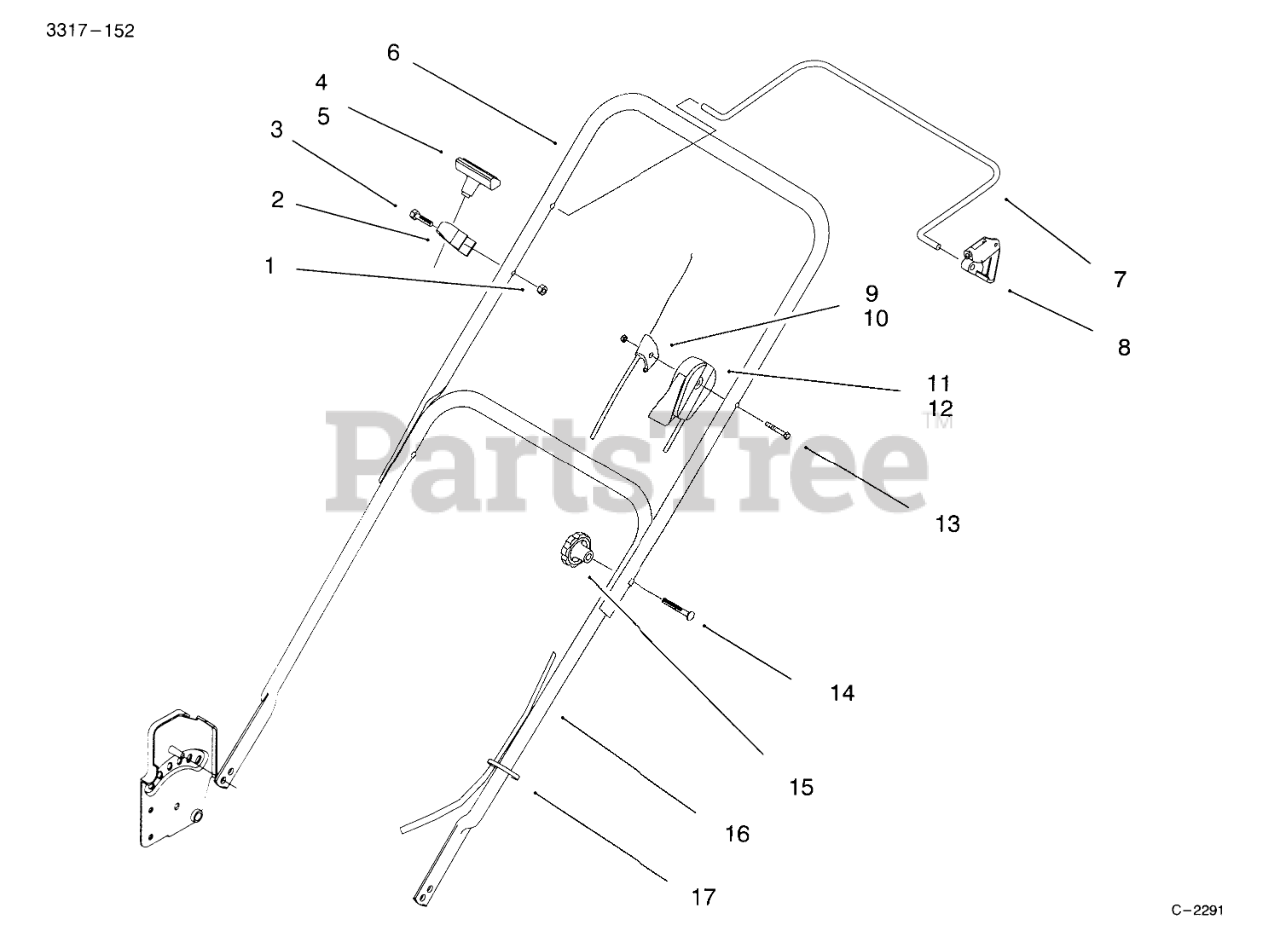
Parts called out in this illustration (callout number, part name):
1	NUT-LOCK, NI
2	GUIDE-ROPE
3	SCREW-HH
4	HANDLE-START
5	CLIP-STARTER
6	Handle-Upper
7	Bar-Control
8	STOP-PIVOT
9	CABLE - BRAKE
10	CABLE-BRAKE SERVICE
11	CABLE - THROTTLE
12	CABLE-THROTTLE
13	SCREW-HANDLE
14	SCREW-HANDLE
16	Handle-Lower
17	TIE-CABLE
